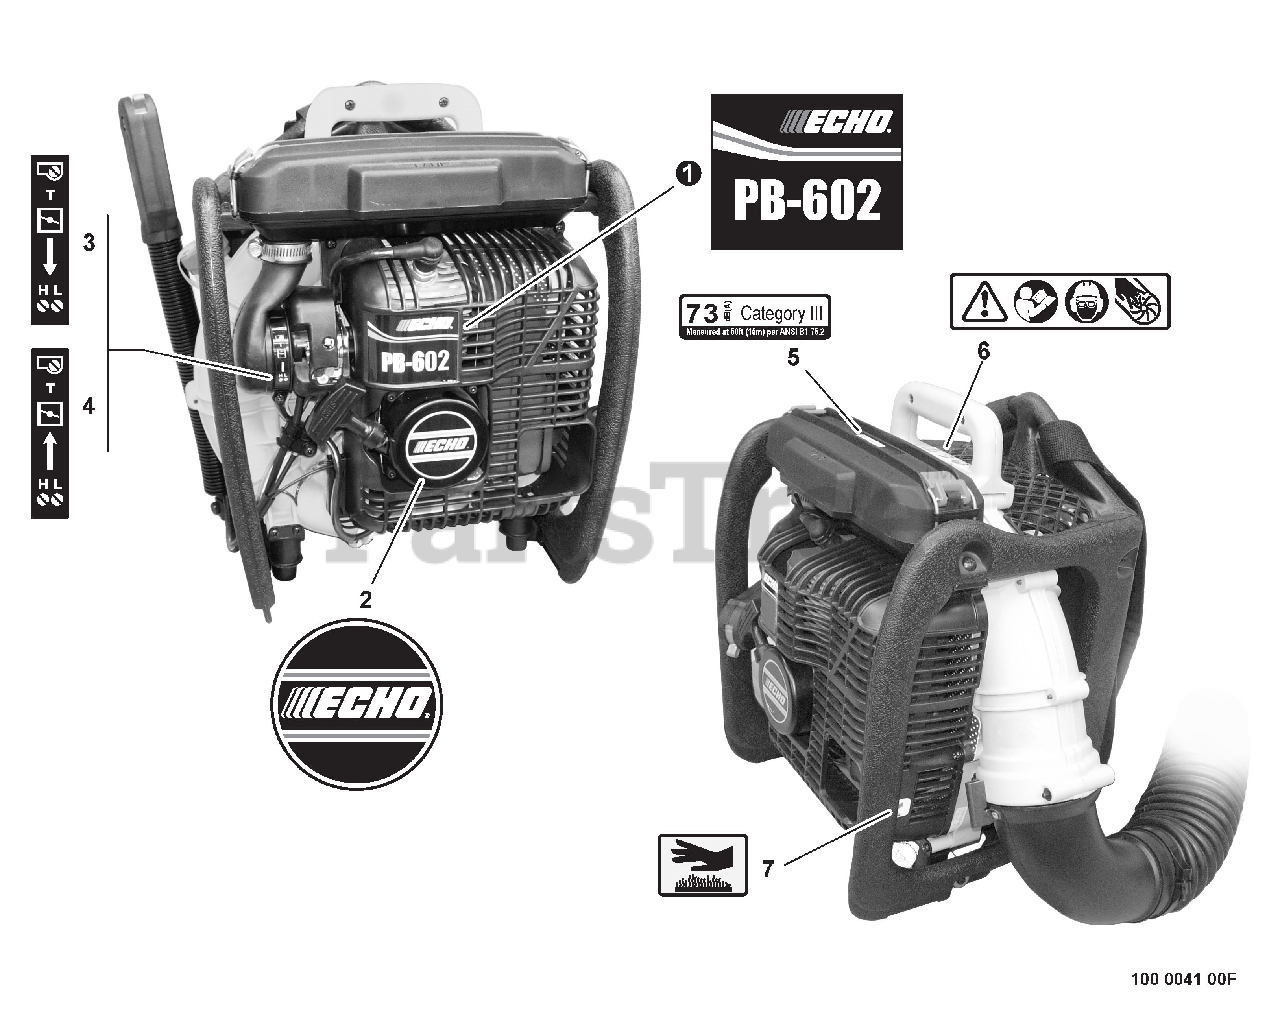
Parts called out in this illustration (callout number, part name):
1	LABEL - MODEL PB-602
2	LABEL - ECHO
3	LABEL - CHOKE
4	LABEL - CHOKE
5	LABEL - NOISE 73dB(A) CAT III
6	LABEL - CAUTION
7	LABEL - HOT SURFACE
